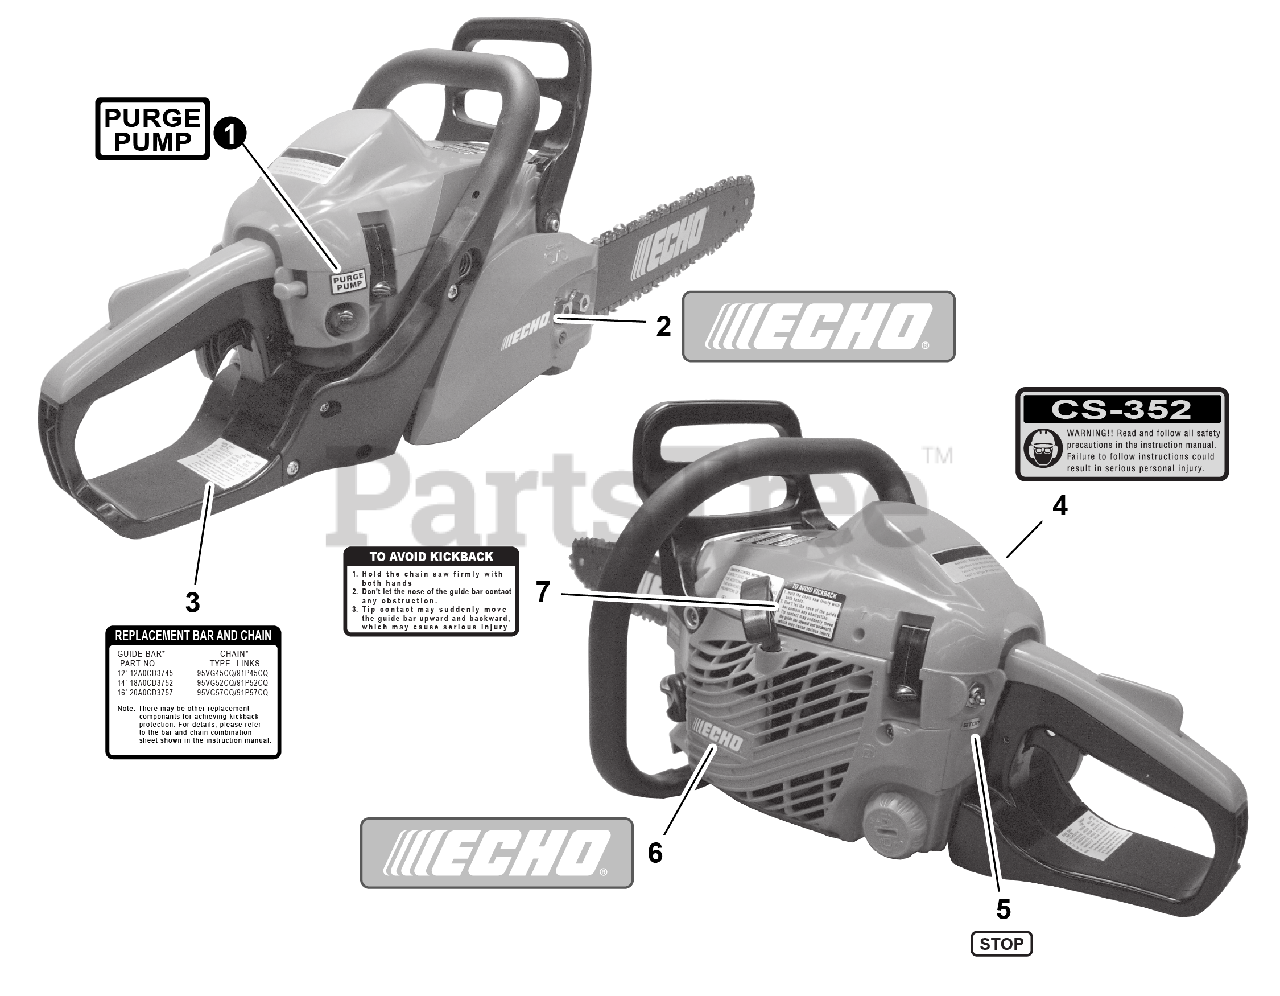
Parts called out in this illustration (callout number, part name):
1	LABEL, PURGE PUMP
2	LABEL, ECHO
3	LABEL, BAR & CHAIN
4	LABEL, CS-352
5	LABEL, STOP
6	LABEL, ECHO
7	LABEL, UL - KICK BACK
